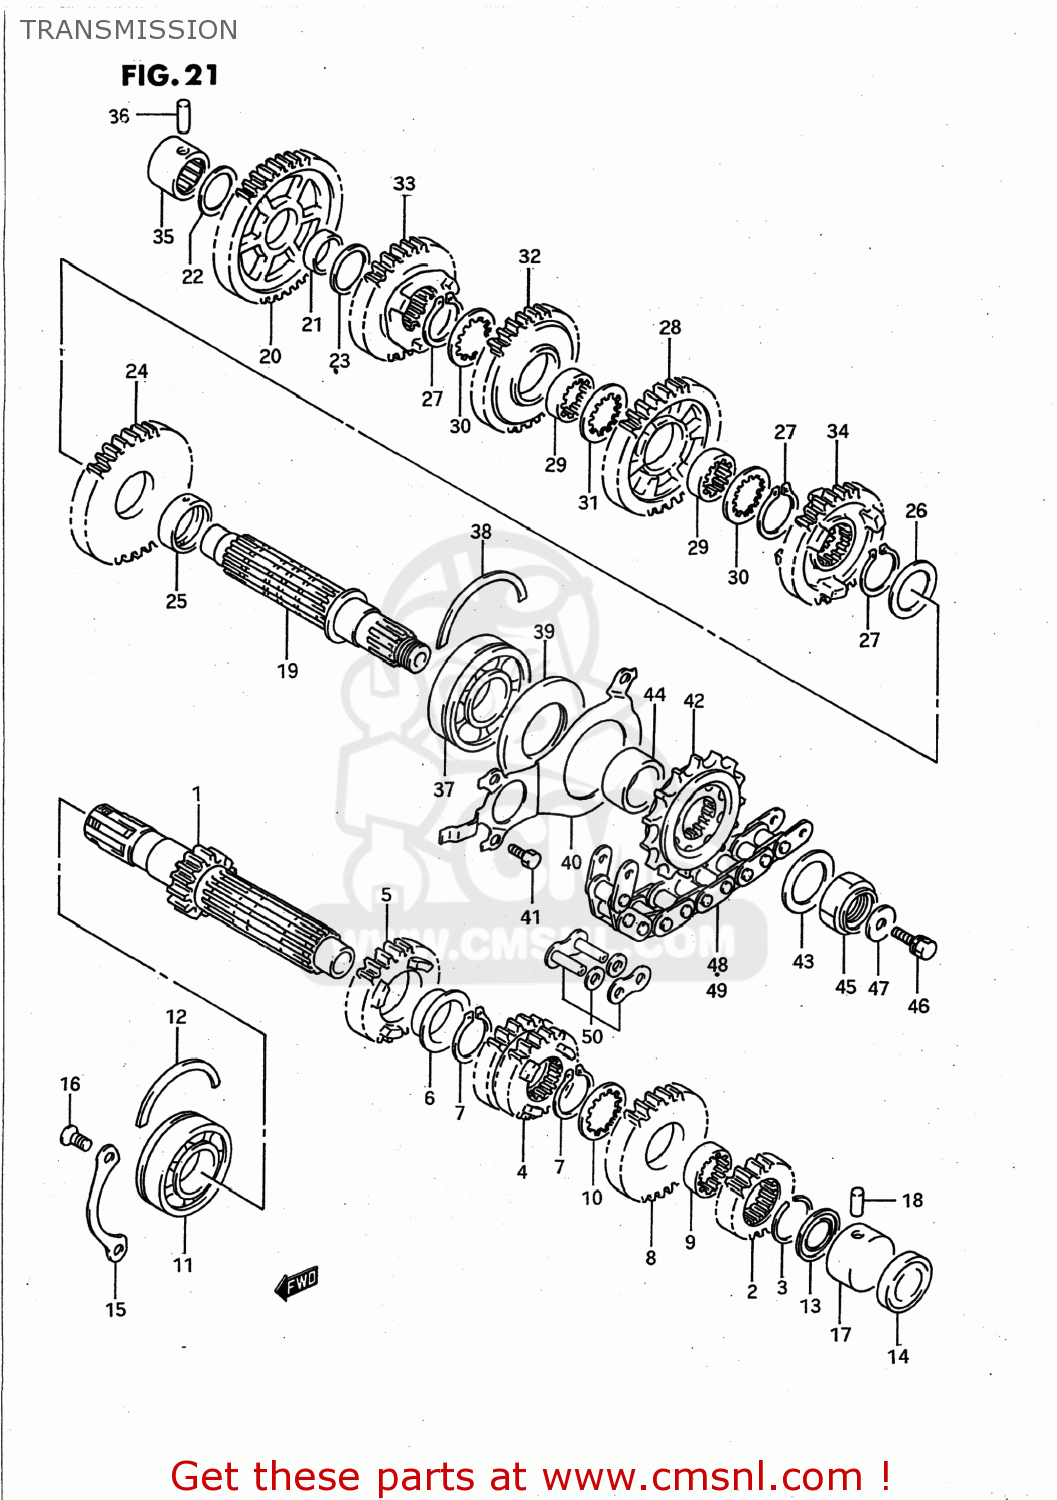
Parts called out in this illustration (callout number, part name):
1	SHAFT,COUNTER
2	GEAR,SECOND DRIVE
3	CIRCLIP
4	GEAR,THIRD & FOURTH DRIVE
5	GEAR,FIFTH DRIVE
6	BUSH(28X32X2)
7	CIRCLIP
8	GEAR,SIXTH DRIVE
9	BUSHING,SIXTH DRIVE GEAR
10	WASHER,LOCK
11	BEARING(25X62X17)
12	C-RING
13	SEAL,OIL(20X31.2X2.7)
14	CAP,COUNTER SHAFT,L
15	RETAINER,CNTR SHAFT BEARING
16	SCREW
17	BEARING(20X34X17.5)
18	PIN
19	SHAFT,DRIVE
20	GEAR,1ST DRIVEN(NT:43)
21	BUSH(22X26X9)
22	WASHER
23	WASHER
24	GEAR,2ND DRIVEN
25	BUSHING
26	WASHER, THRUST
27	CIRCLIP
28	GEAR,3RD DRIVEN(NT:33)
29	BUSH,3RD DRIVEN GEAR
30	WASHER,LOCK
31	WASHER,LOCK
32	GEAR,FOURTH DRIVEN
33	GEAR,5TH DRIVEN(NT:29)
34	GEAR,6TH DRIVEN
35	BEARING(20X34X20)
36	PIN
37	BEARING(28X70X18)
38	C RING
39	SEAL,OIL(34.8X70X6)
40	RETAINER,DRIVE SHAFT OIL SEAL
41	BOLT
42	SPROCKET,ENGINE (NT:15)
43	WASHER,THRUST
44	SPACER(25X36X17.7)
45	NUT
46	BOLT
47	WASHER
48	CHAIN ASSEMBLY,DRIVE 50GSV
49	CHAIN ASSEMBLY RK50GSVZ1.1
50	JOINT SET,DRIVE CHAIN
